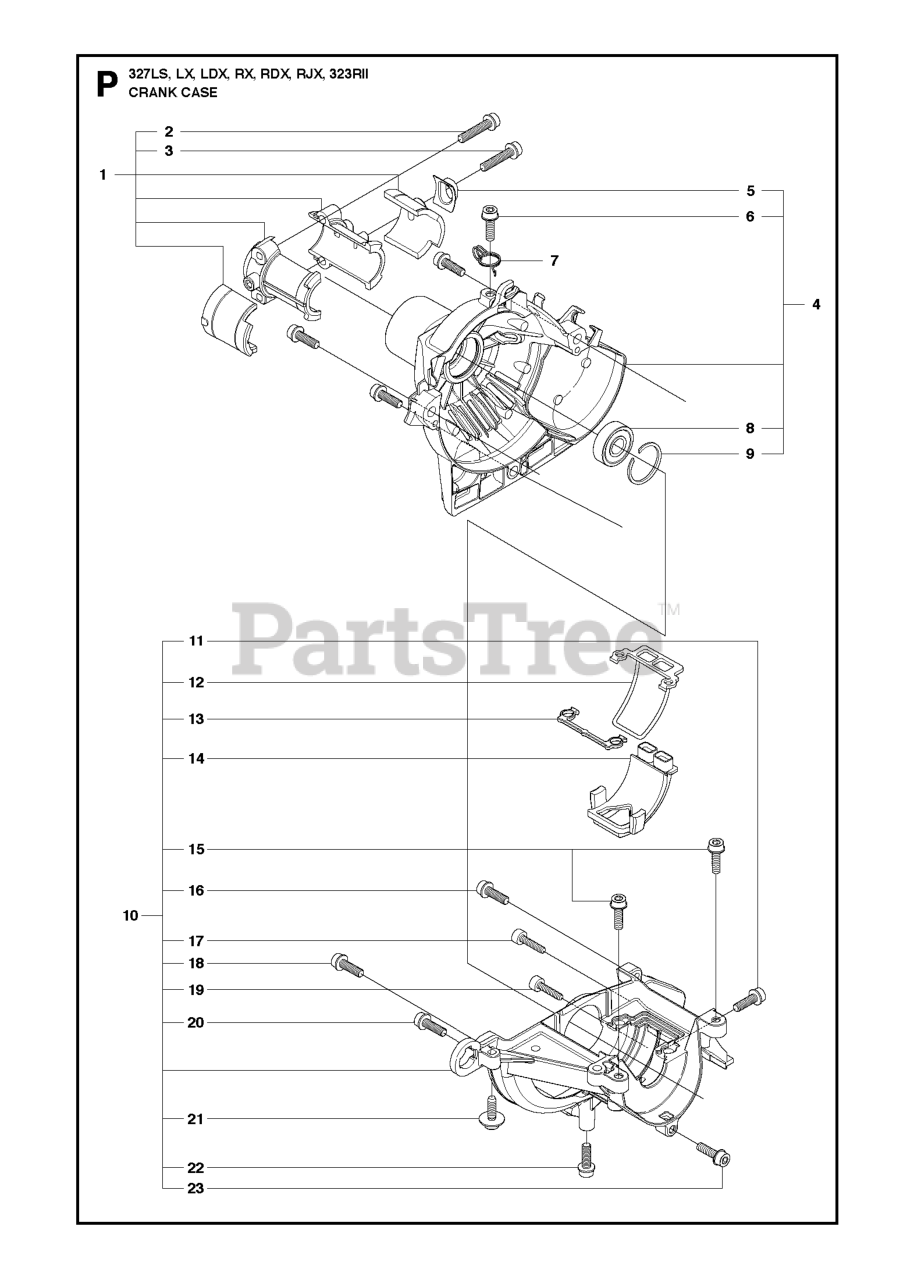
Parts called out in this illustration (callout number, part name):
1	COMPRESION SLEEVE/ISOLATOR SET
4	CLUTCH COVER
5	PROTECTION PLATE
6	SCREW
9	RETAINING RING
10	CRANKCASE
22	SCREW
